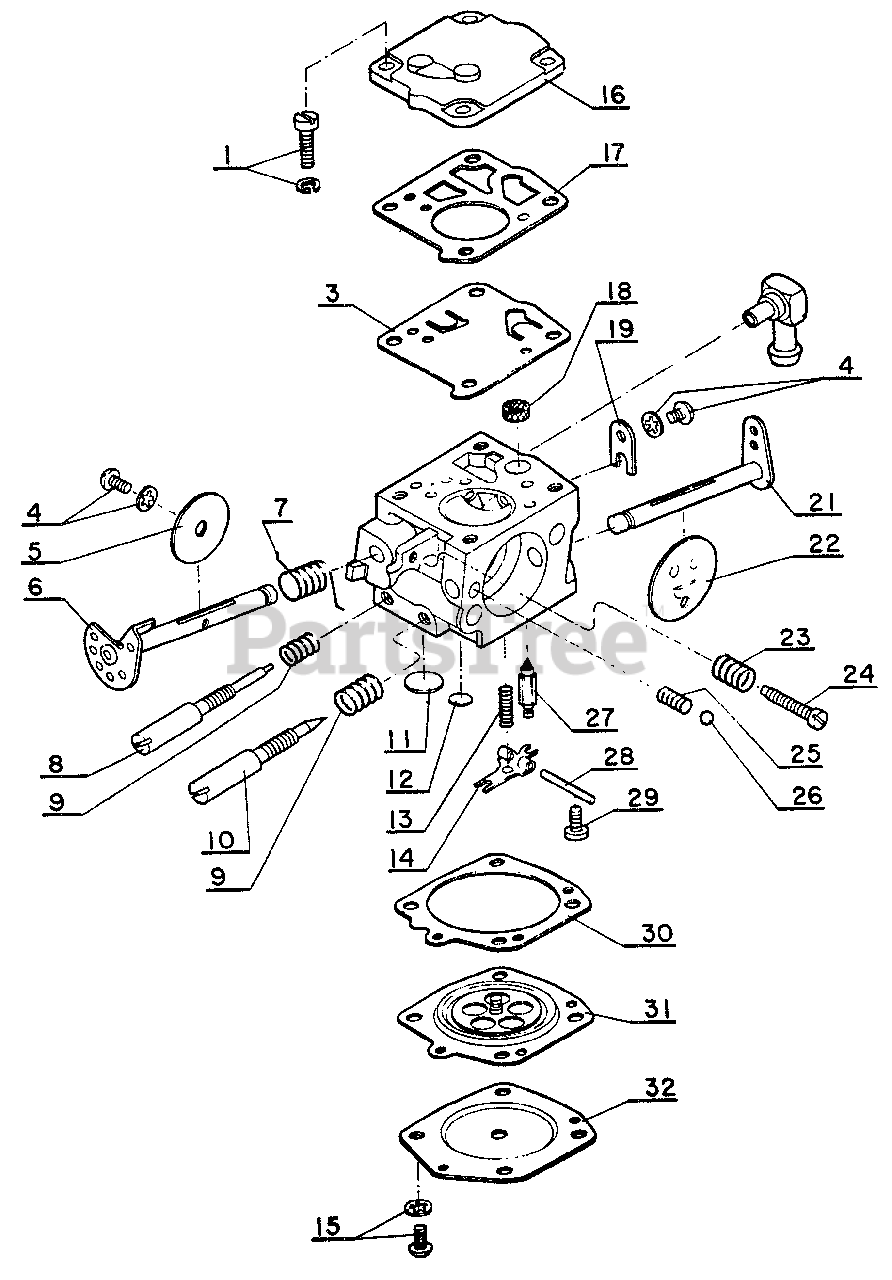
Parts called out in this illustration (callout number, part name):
1	SCREW
3	DIAPHRAGM, PUMP
4	SCREW
5	VALVE, THROTTLE
6	SHAFT, THROTTLE
7	SPRING, RETURN
8	SCREW, IDLE ADJUST
9	SCREW, IDLE ADJUST
10	SCREW, MAIN ADJUST
11	PLUG, WELCH - LARGE
12	PLUG, WELCH - SMALL
13	SPRING, METERING LEVER
14	LEVER, METERING
15	SCREW
16	COVER, PUMP
17	GASKET, PUMP
18	STRAINER
19	RING, RETAINING
21	SHAFT, CHOKE
22	VALVE, CHOKE
23	SPRING, IDLE ADJUST
24	SCREW, IDLE ADJUST
25	SPRING, CHOKE SET
26	BALL, CHOKE SET
27	VALVE, INLET NEEDLE
28	PIN, METERING LEVER
29	SCREW, METERING LEVER PIN
30	GASKET, DIAPHRAGM
31	DIAPHRAGM
32	COVER, DIAPHRAGM
